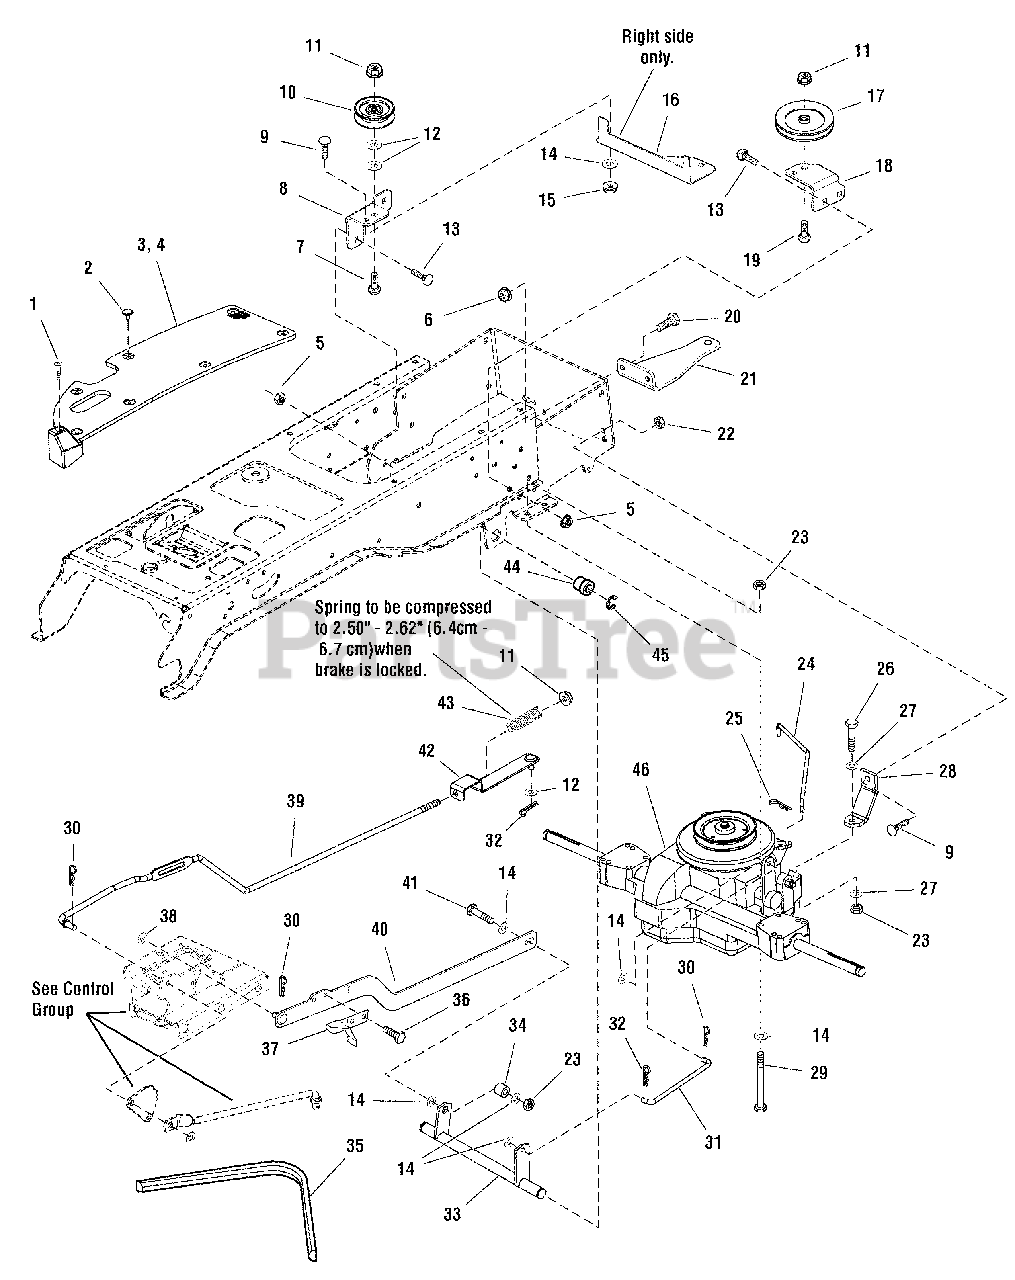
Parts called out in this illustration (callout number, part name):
1	SCREW, Pan Head Torx Taptite, 1/4-20 x 1-1/4
2	FASTENER, Panel 3/4 Head
3	PAD, Footrest, RH Black Vinyl Textured
4	PAD, Footrest with Differential Lock, LH Black Vinyl Texture
5	NUT, Hex KEPS, 3/8-16
6	NUT, Hex Flange, 3/8-16 Whiz Lock Large
7	CARRIAGE BOLT, 3/8-16 x 1-3/4 G5
8	SUPPORT, Idler, RH
9	CARRIAGE BOLT, 5/16-18 x 3/4 G5
10	PULLEY, 3 in.
11	NUT, Hex Flange3/8-16 ESNA
12	WASHER, 3/4
13	CARRIAGE BOLT, 3/8-16 x 1 G5
14	WASHER, 5/16
15	NUT, Hex Keps Conical Washer, 5/16-18
16	BRACKET, Chute Locator
17	PULLEY, Idler, 4 in.
18	SUPPORT, Idler, LH
19	CARRIAGE BOLT, 3/8-16 x 1-1/2 G5
20	CAPSCREW, Hex Head, 3/8-16X1.000 G5 BLK
21	DRAWBAR, 1/4 in. Thick
22	NUT, Hex KEPS, 5/16-18
23	NUT, Hex Lock ESNA Light, 5/16-18
24	ROD, Transmission Release
25	CLIP, Hair Pin Spring
26	CAPSCREW, Hex Head, 5/16-18 x 2 G5
27	WASHER, 5/16
28	STRAP, Torque, 1/4 Thick 4 in. Long
29	CAPSCREW, Hex Head, 5/16-18 x 2-3/4 G5
30	PIN, Quick
31	ROD, Control
32	PIN, Cotter
33	SHAFT & ARMS ASSEMBLY, Control
34	SPACER, Powered Metal
35	V-BELT, Drive Belt
36	CAPSCREW, Hex Washer Head Taptite, 5/16-18 x 1/2
37	ACTUATOR, Switch
38	WASHER, 3/8
39	ROD, Brake
40	ARM & PIN ASSEMBLY, Speed Control
41	CAPSCREW, Hex Head, 5/16-18 x 1 G5
42	BRACKET & PIN ASSEMBLY, Brake
43	SPRING, Compression
44	BUSHING, Nylon
45	RING, E Retaining
46	TRANSMISSION ASAEMBLY, Tuff Torq K46BF
